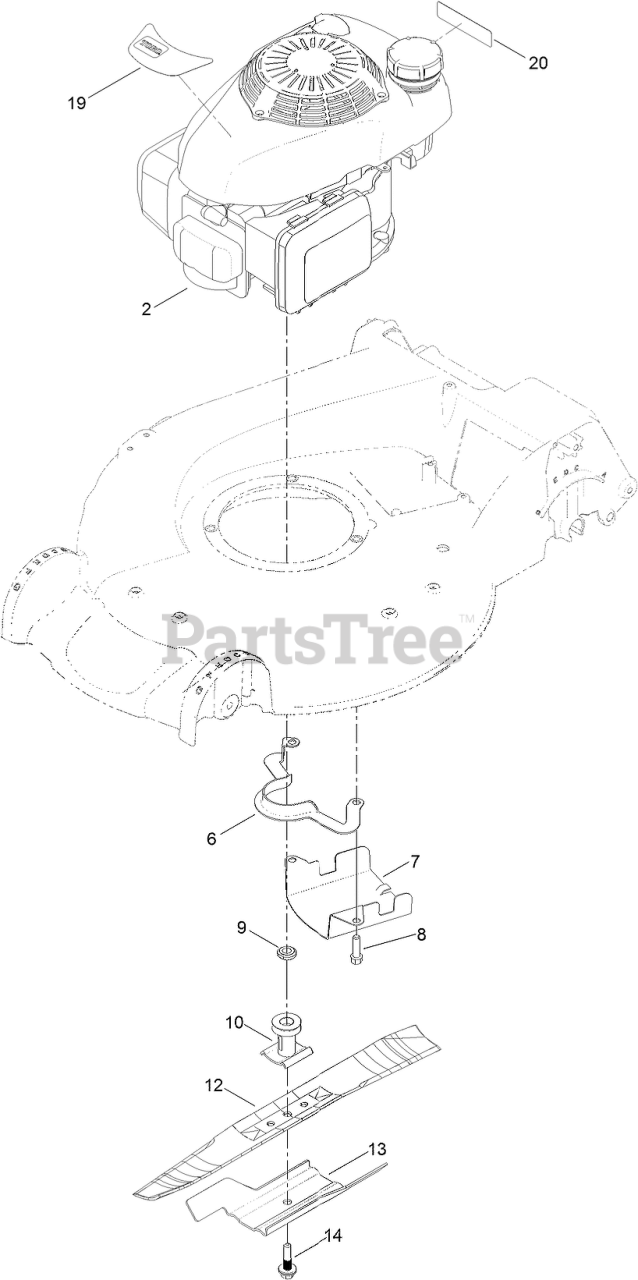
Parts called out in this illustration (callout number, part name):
6	GUIDE-BELT
7	SHIELD-GRASS
8	SCREW-TAPTITE
9	Spacer-Driver
10	DRIVER-BLADE
12	BLADE-RECYCLING
13	Accelerator-Blade
14	BOLT-BLADE
19	DECAL-SHROUD, HONDA
20	DECAL-ARRESTER, SPARK
